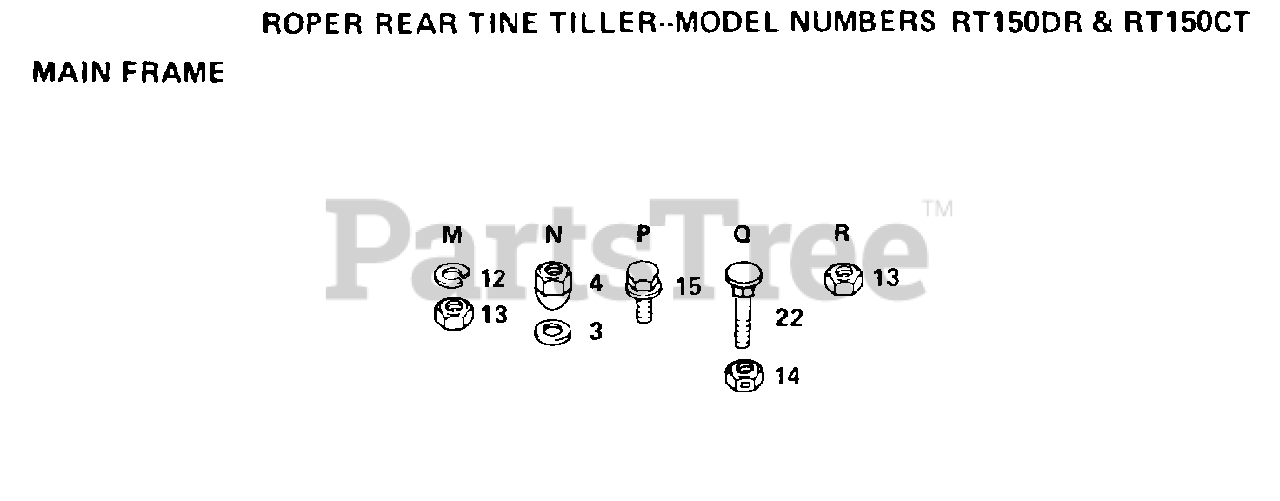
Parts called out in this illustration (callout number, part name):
3	WASHER
4	NUT TI
12	LOCKWASHER
13	NUT.HEX.3/8-16UNC
15	SCREW TI
